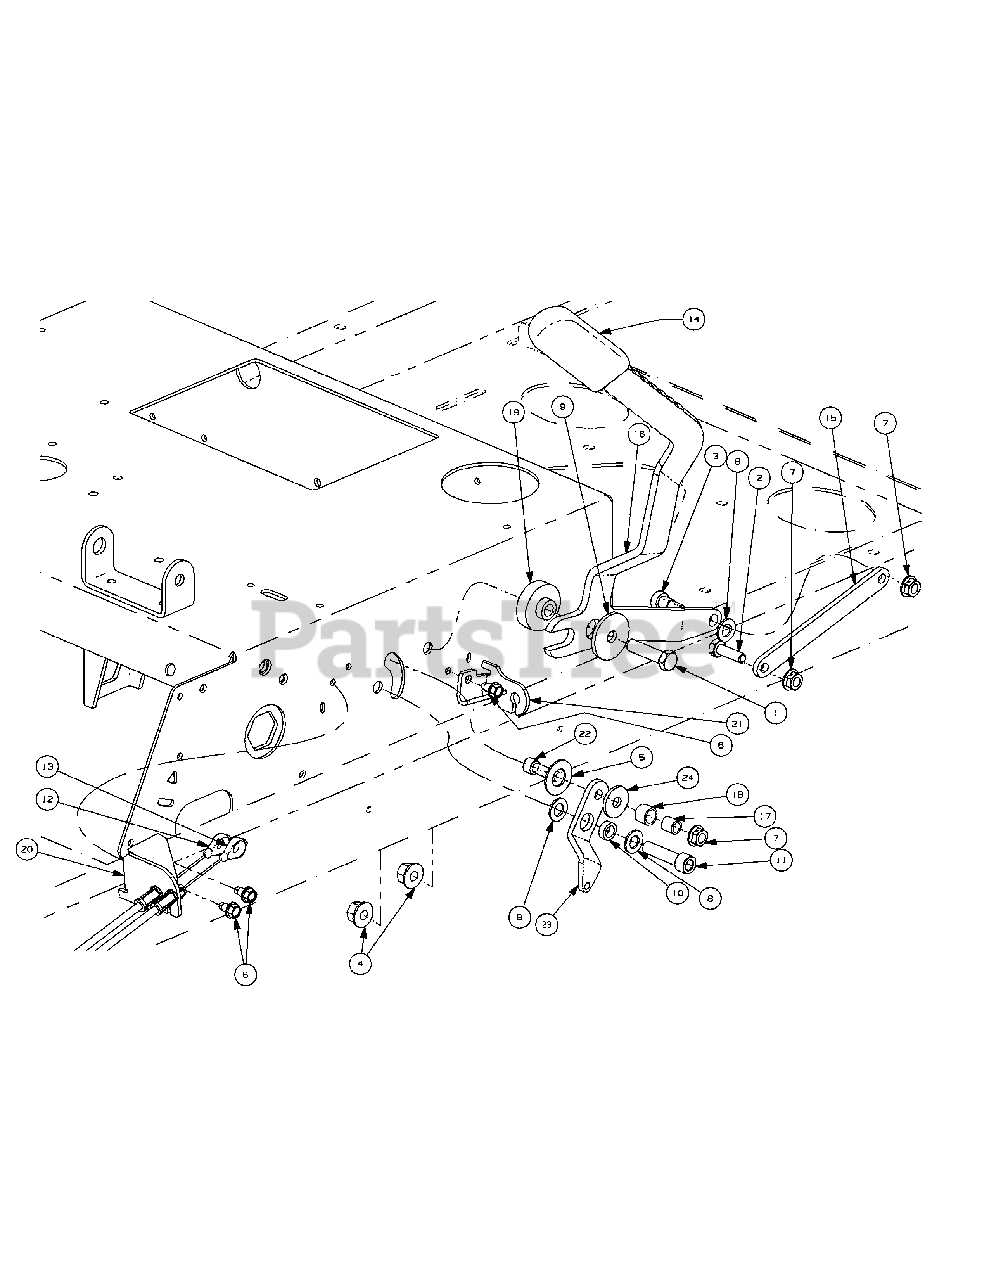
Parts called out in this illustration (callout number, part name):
1	Hex Head Cap Screw, 3/8-16 x 1.50
2	Hex Head Cap Screw, 5/16-18 x 1.00
3	Shoulder Bolt, 3/8 x 3/8
4	Hex Nut, 3/8-16 Flange Lock
5	Slide Washer
6	Screw, TT, 1/4-20, 0.5, Hex Index Washer
7	Nut, 5/16-18, Flange Lock
8	Washer, .375 x .738 x .063
9	Flat Washer, .390 x 1.5 x .134
10	Spacer, .380 x .563 x .196
11	Sockethead Capscrew, 3/8-16 x 1.50
12	Left Hand Brake Cable
13	Right Hand Brake Cable
14	Parking Brake Grip
15	Brake Link Plate
16	Brake Handle
17	Spacer, .322 ID x .438 OD x .44
18	Spacer, .442 ID x .563 OD x .405
19	Step Hub, .379 x 1.5 x .257/.400
20	Brake Cable Mounting Bracket
21	Brake Cable Mounting Bracket
22	Sockethead Capscrew, 5/16-18 x 1.00
23	Lockout Lever Plate
24	Washer, .345 x 1.00 x .100
